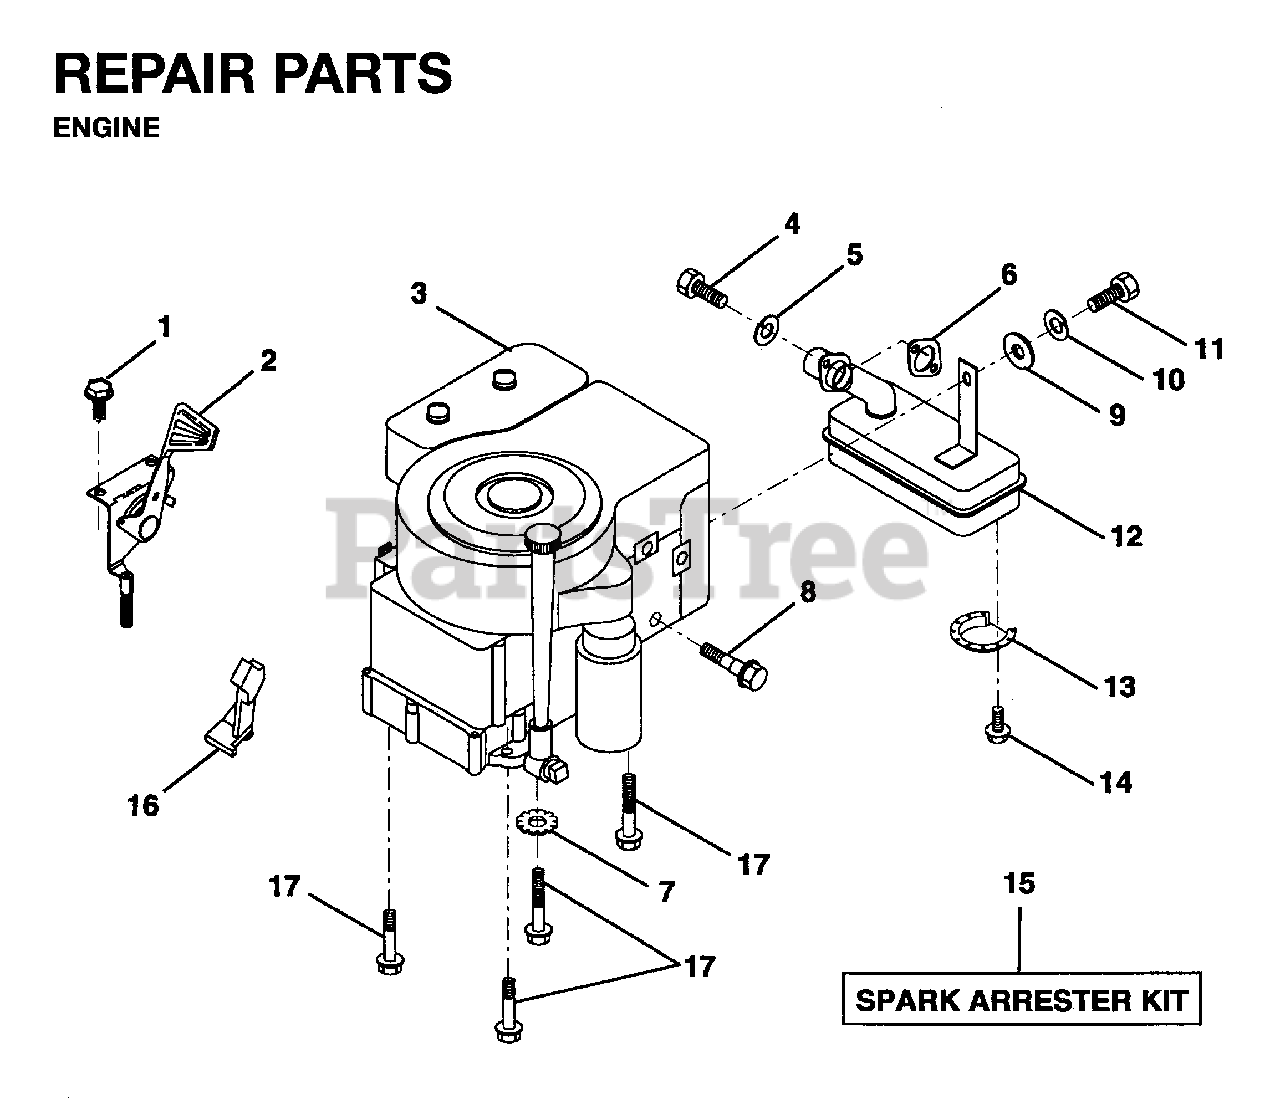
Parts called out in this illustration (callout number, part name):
2	THROTTLE CONTROL
4	SCREW
5	LOCKWASHER
6	GASKET ENGINE
7	WASHER, LOCK 3/8
9	WASHER - 26X6.5X1.6
10	LOCKWASHER
13	DEFL MUFFLER LTV
14	SCREW
15	ARRESTER SPARK (OPTIONAL)
16	STOP THROTTLE
17	BOLT
